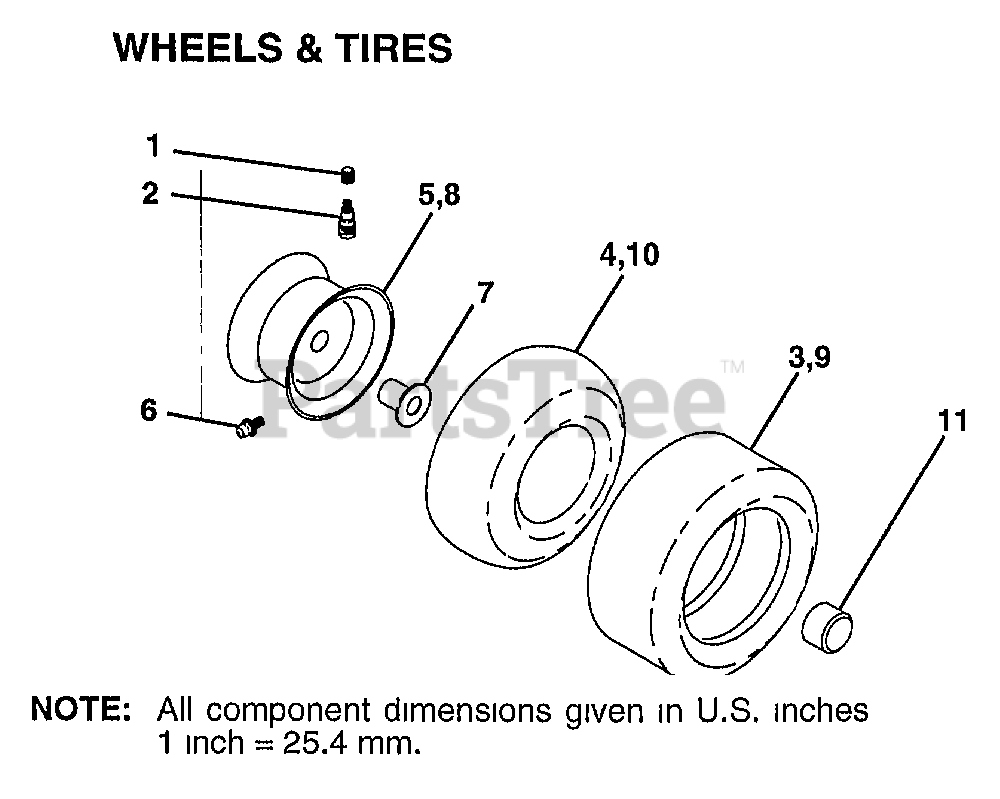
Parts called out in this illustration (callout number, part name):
1	VALVE CAP
2	VALVE STEM LT
4	TUBE.5.3/4.5/6
5	"RIM,FRT T"
6	FITTING LT
7	"FLANGE, BEARING"
8	"RIM 8"""
10	TUBE.18X9.5-8
11	HUB CAP
